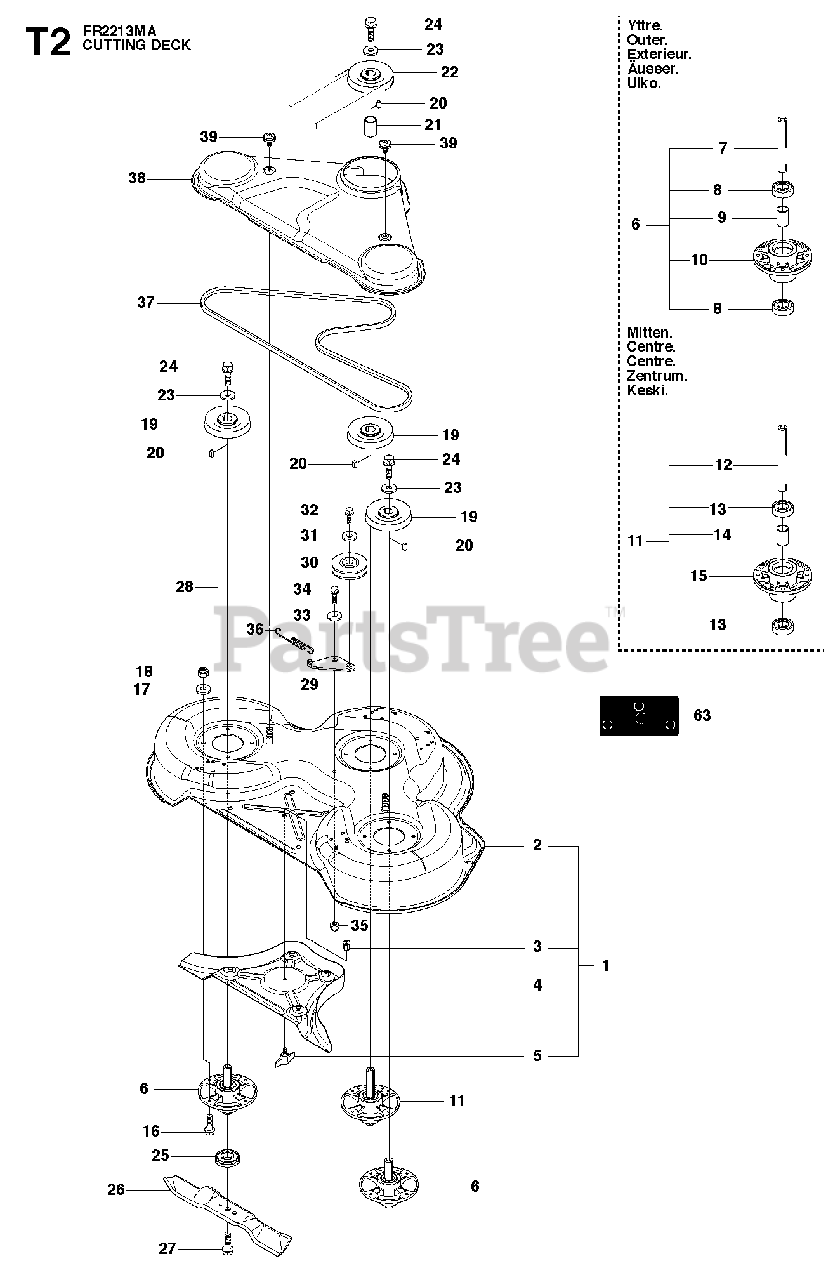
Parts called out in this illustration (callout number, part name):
3	NUT
6	RP SPINDLE ASSY
7	SHAFT
8	BEARING
9	SPACER
10	BEARING HOUSING
13	BEARING
14	SPACER
15	BEARING HOUSING
17	WASHER BRB 8.4X17
18	LOCKNUT M8
29	BRACKET
30	PULLEY
31	SPACER
32	BOLT
33	WASHER
35	LOCKNUT M8
